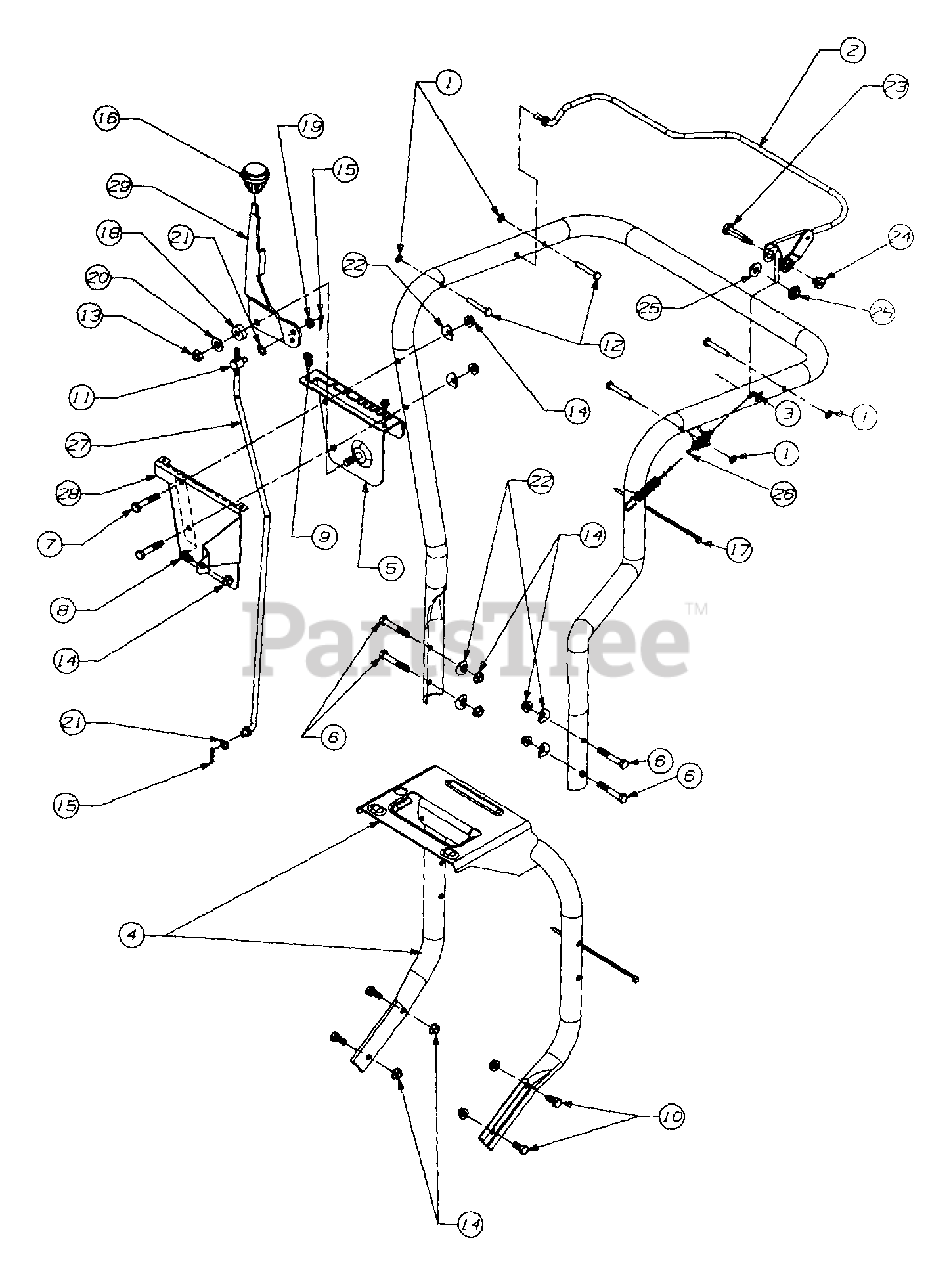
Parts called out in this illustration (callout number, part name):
7	SCREW-HEX
8	SCREW-HEX
9	SCREW-HEX
10	SCREW-HEX
11	FERRULE
12	PIN-STUD
13	NUT-HEX LOCK
14	NUT-HEX LOCK
15	PIN-COTTER
16	KNOB-SHIFT
17	CABLE TIE
18	WASHER-RUBBER
19	WASHER-FLAT
20	WASHER-FLAT
21	WASHER-SPRING
22	WASHER-SADDLE
23	SCREW-SHOULDER
24	NUT-SHOULDER
25	BEARING-FLANGE PLASTIC
26	CABLE-CLUTCH
27	ROD-SHIFT
